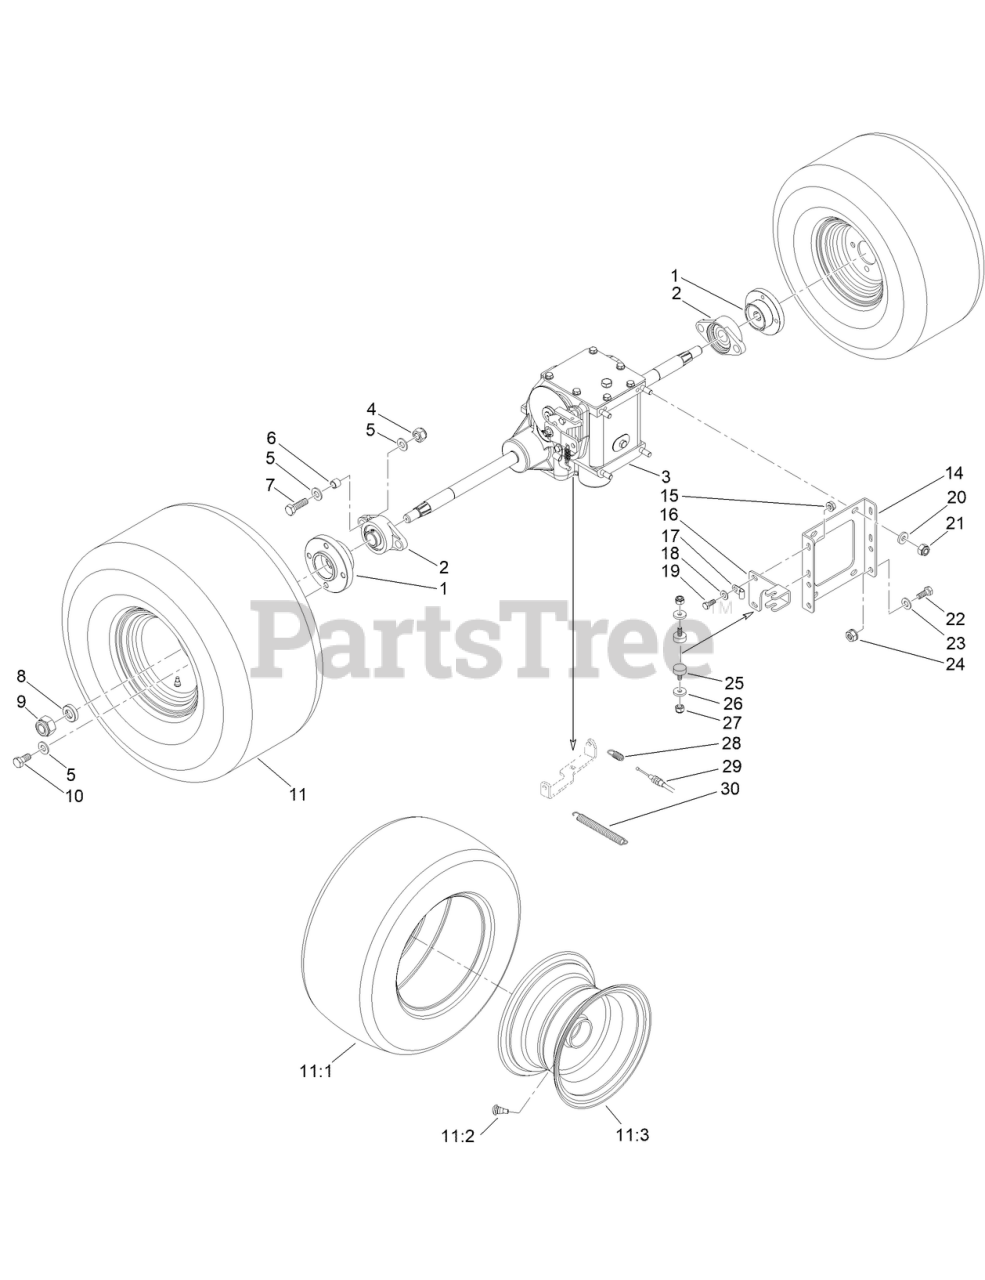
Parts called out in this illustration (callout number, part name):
1	HUB, FRONT WHEEL
2	BEARING
3	TRANSMISSION GEARBOX ASSY
5	WASHER
6	SPACER
7	SCREW-HH
8	WASHER
9	NUT-HH
11	FRONT WHEEL ASM
11:2	VALVE-TIRE
14	SUPPORT, TRANSMISSION GEARBOX
16	RETAINER, CLUTCH
17	GROMMET
18	WASHER
20	WASHER
23	WASHER
25	SHOCK ABSORBER
26	WASHER-PLAIN
28	SPRING, DIFF LOCK CABLE
29	CABLE, DIFF LOCK
30	SPRING, DIFF LOCK LEVER
